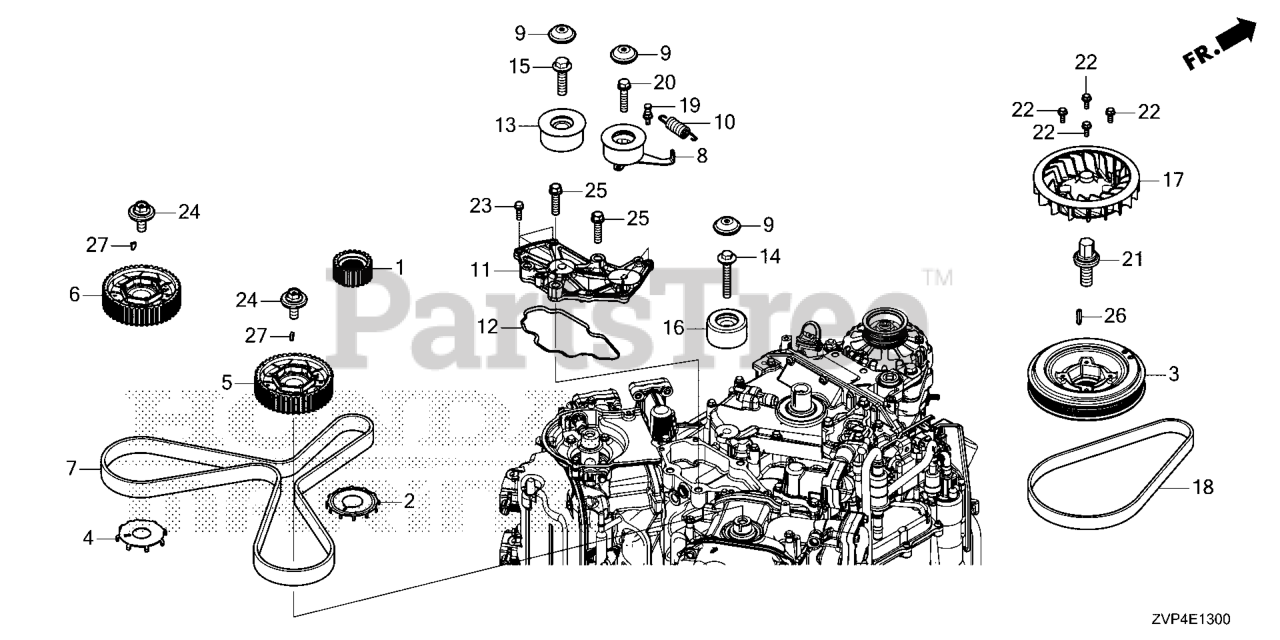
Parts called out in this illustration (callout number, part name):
1	PULLEY, TIMING BELT DRIVE
2	PLATE, CRANK PULSER
3	PULLEY, CRANKSHAFT
4	PLATE, TDC PULSER
5	PULLEY, T/B DRIVEN R
6	PULLEY, T/B DRIVEN L
7	BELT (197YU26)
8	TENSIONER COMP, T/B
9	CAP, TIMING BELT TENSIONER
10	SPRING, TIMING BELT ADJUSTING
13	IDLER, TIMING BELT (KOYO SEIKO)
14	BOLT, IDLER
15	BOLT, T/B IDLER
16	IDLER B, TIMING BELT
17	FAN, COOLING
18	BELT, ALTERNATOR (6PK745 M-180)
19	BOLT, T/B ADJ SPG
20	BOLT, FLANGE (10X43)
21	BOLT-WASHER (16X49)
22	BOLT, FLANGE (6X16)
23	BOLT, FLANGE (6X22)
24	BOLT-WASHER (12X35)
25	BOLT, FLANGE (10X40)
26	KEY (4.5X24)
27	KEY, SPECIAL
